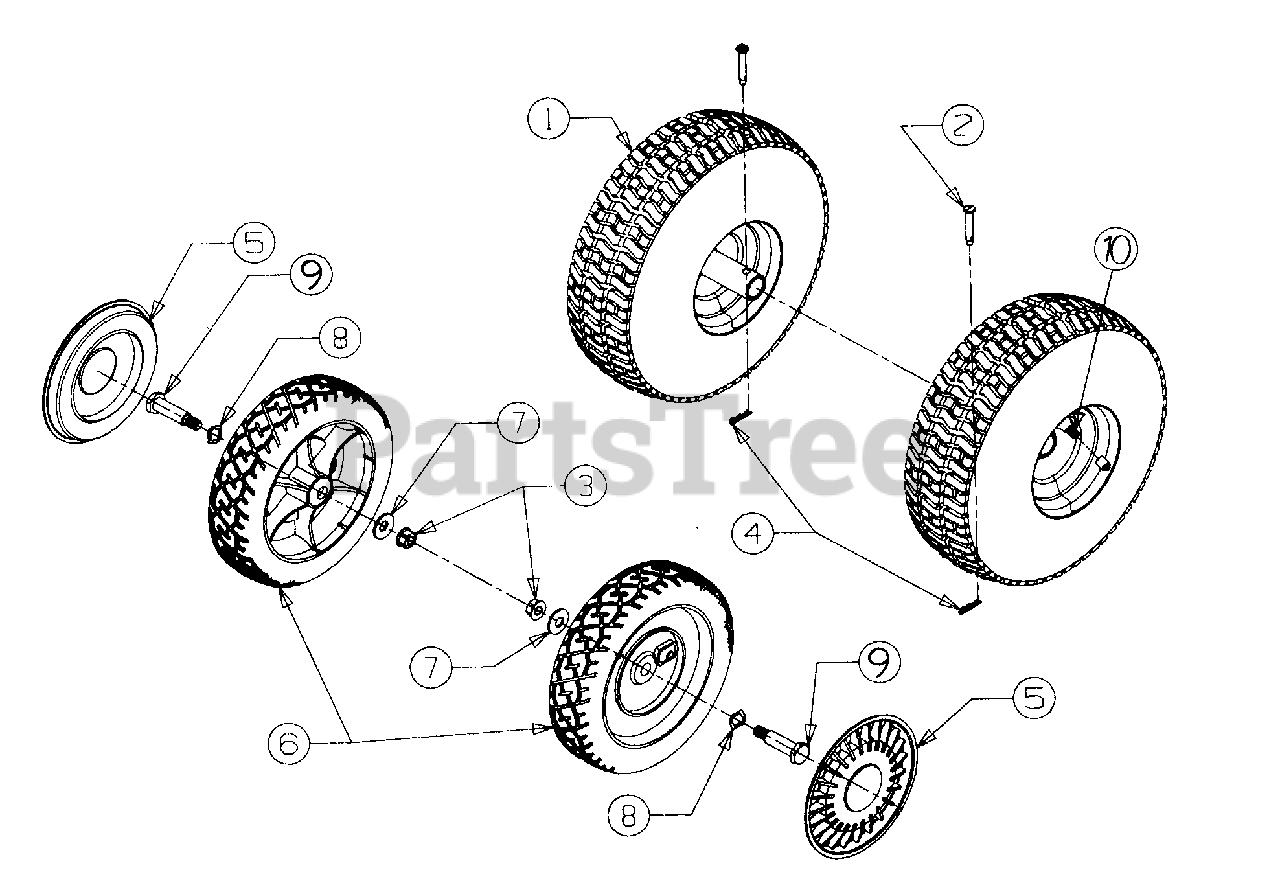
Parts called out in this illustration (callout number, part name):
2	PIN-CLEVIS
3	NUT-HEX FLANGE
4	PIN-COTTER
5	HUB CAP
6	WHEEL
7	WASHER-BELL
8	WASHER-WAVE
9	SCREW-SHOULDER
10	VALVE STEM
